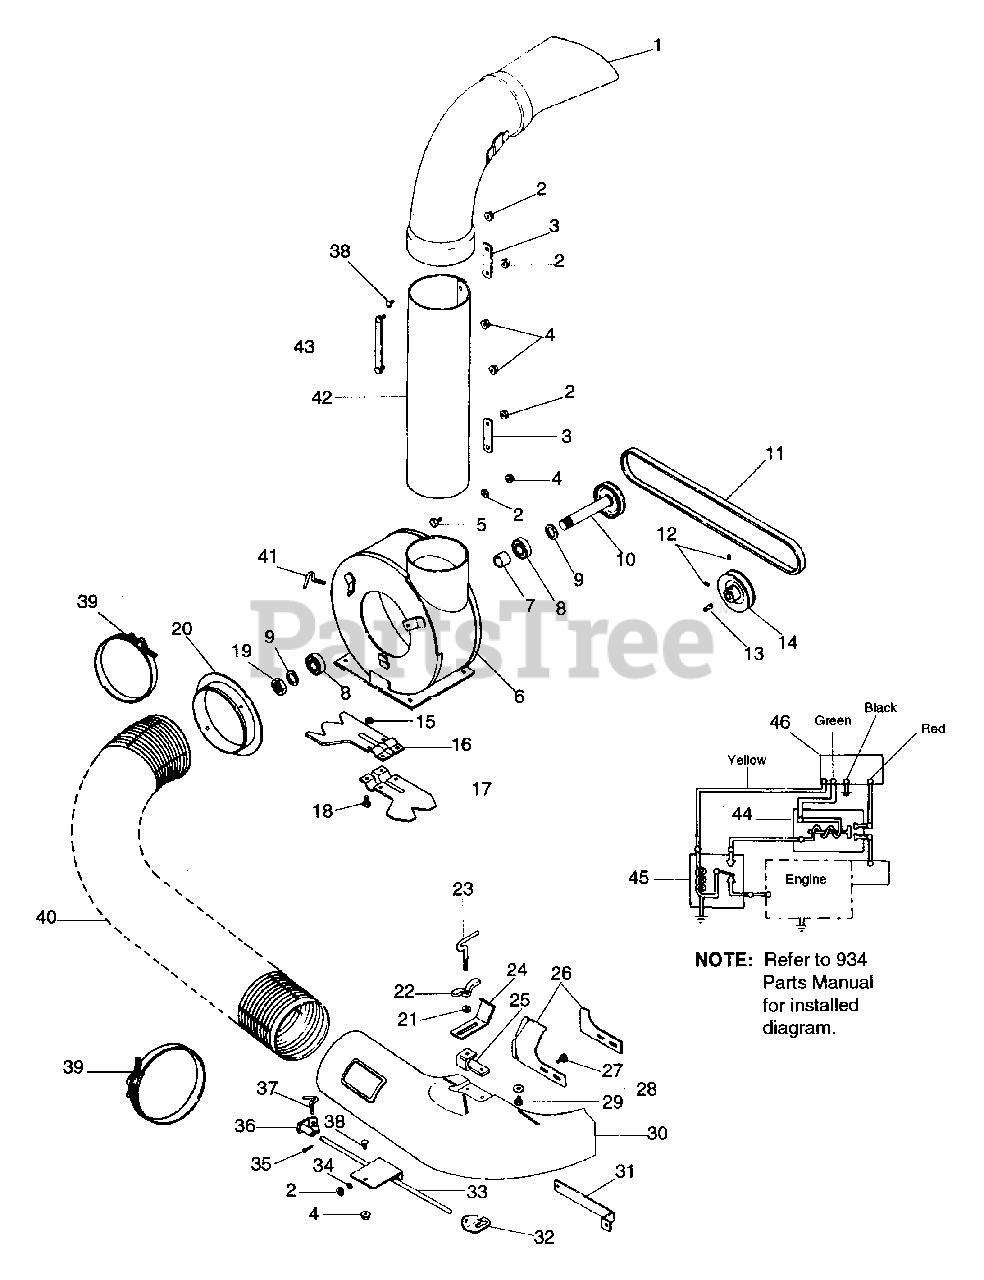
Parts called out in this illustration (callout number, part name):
1	UPPER ELBOW
2	NUT-LK-CTR .250-20 PL
4	NUT-LK-FLG .250-20 PL
5	BLT-HEX .25-20X.75 PL GR5
6	G-FAN HSG
7	SPACER 1.010X1.250X.924
8	BRG-BALL 1.0X2.0X.56
9	WSHR-FL-STL 1.015X1.500X.125
10	SPINDLE WELDMENT
11	BELT,HA RAW COGGED
12	SCR-SET .25-20X.38 SKHCUP OH
13	KEY-SQ .188X1.0X.188 SAE 8630
14	PLY-V 4.00 X .75 W/KEY ADAMS
15	NUT-LK .312-18 GR A PL
16	FAN BLADE
17	FAN BLADE
18	BLT-HEX .31-18X.63 PL GR 2
19	NUT-LK-JAM 1.0-14 PL
20	HOSE ADAPTER
21	WSHR-FL-STL .38X.875X.083 PL
22	WING NUT, .312-18
23	CLAMP SCREW
24	DEFLECTOR STOP
25	COLLECTOR BOOT CLAMP
26	VAC PLATE
27	BLT-HEX .25-20X.63 PL GR2
28	WSHR-FL-STL .281X1.250X.048PL
29	BLT-HEX .25-20X.38 PL GR2
31	BRACKET - STOP
32	BOOT CLIP
33	BOOT BRACE
34	WSHR-FL-STL .250X.562X.049 PL
35	PIN-COTR .09X.75 PL
36	BOOT CLAMP
37	CLAMP SCREW
38	BLT-RDHDSQNK .25-20X.50 SHT PL
39	CLAMP-HOSE WRM 2.13/8.62X.56
40	HOSE 7 X 44.5
41	CLAMP SCREW
42	UPPER TUBE BLANK
44	SOLENOID
45	RELAY
46	HTH VAC WIRE HARNESS
47	SPRING SWITCH, PULL ON
